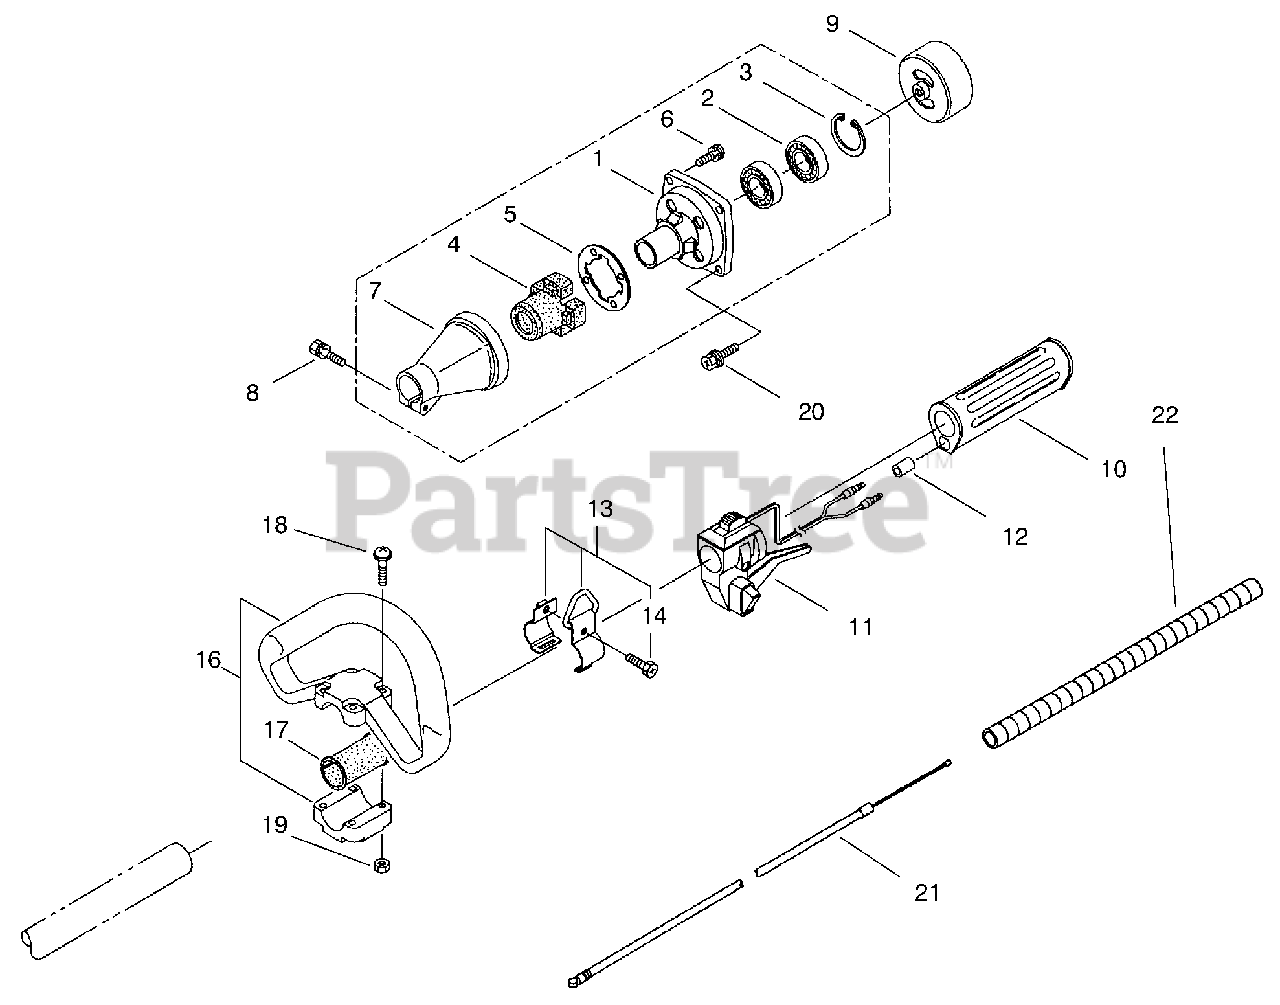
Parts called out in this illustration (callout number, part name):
1	Bearing Case
3	Snap Ring
7	Driveshaft Tube Adapter
9	Clutch Drum
10	Shaft Grip
11	Throttle Trigger
12	Outer Guide
13	Hanging Bracket Assembly (Incl. Ref. #14)
16	Loop Handle
21	Throttle Cable
22	Plastic Tube
